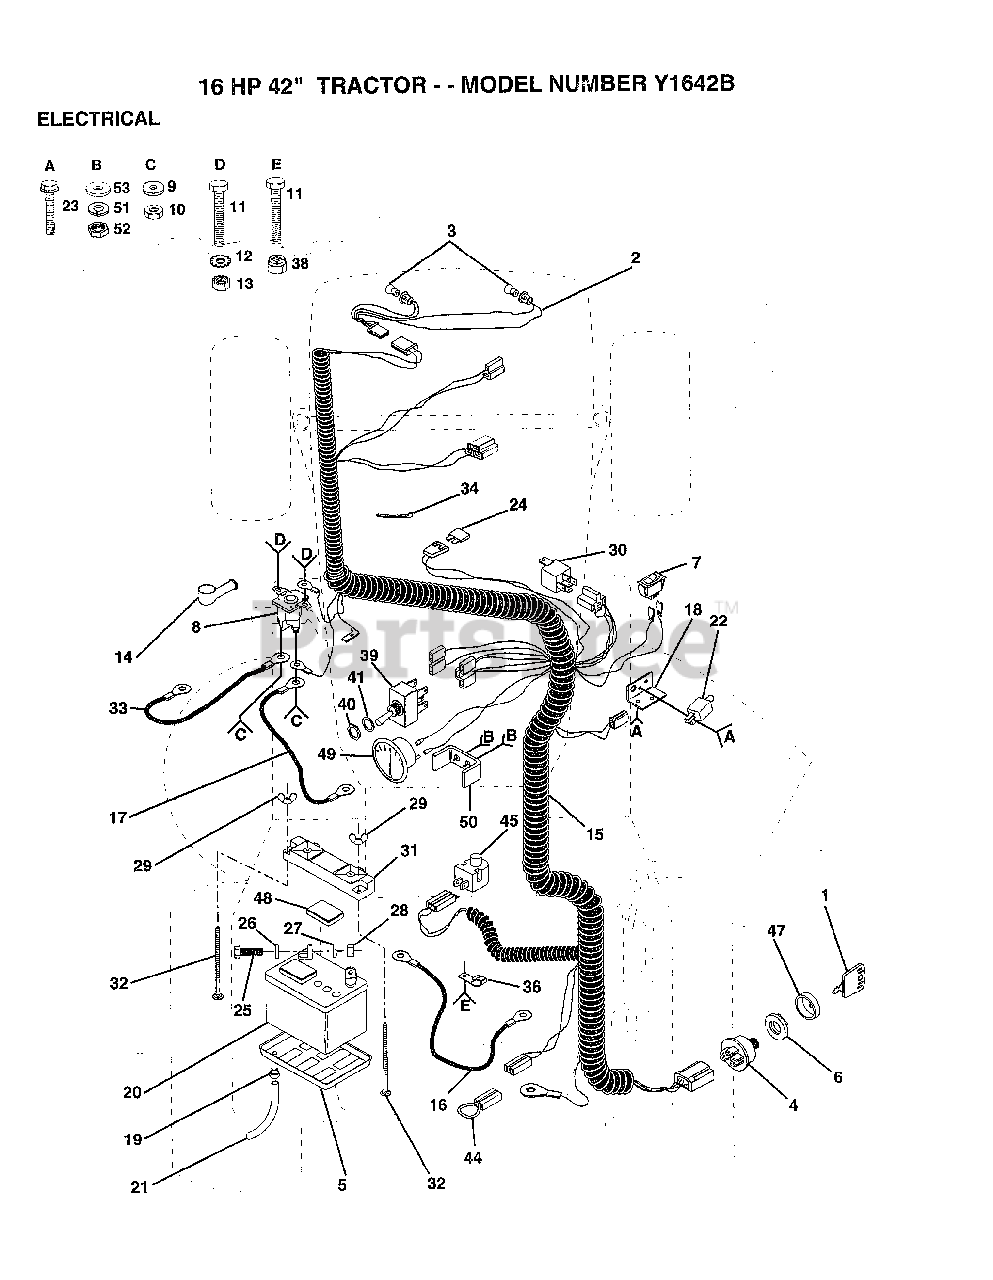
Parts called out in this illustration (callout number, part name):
1	KEY
2	"HARNESS,LIGHT SOC"
5	"TRAY T, BATTERY"
6	NUT IGNITION
7	SWITCH LT
10	NUT
11	BOLT
13	NUT
15	"HARNESS,IGNITION"
16	CABLE T
17	CABLE-BATTERY T
18	BRACKET LT
19	HOSE CLAMP T
21	"DRAIN TU T, BATT"
22	SWITCH-INTER. GT
23	SCREW
24	FUSE HYT
25	BOLT LT
26	WASHER
27	LOCKWASHER
30	RELAY ASSY T
32	BOLT
33	"CABLE T, BATTERY"
34	WIRE TIE
36	CLIPT
40	HEX NUT T
41	WASHER
45	SWITCH SEAT
48	"CAP,BATTERY "
49	AMMETER T
53	WASHER
